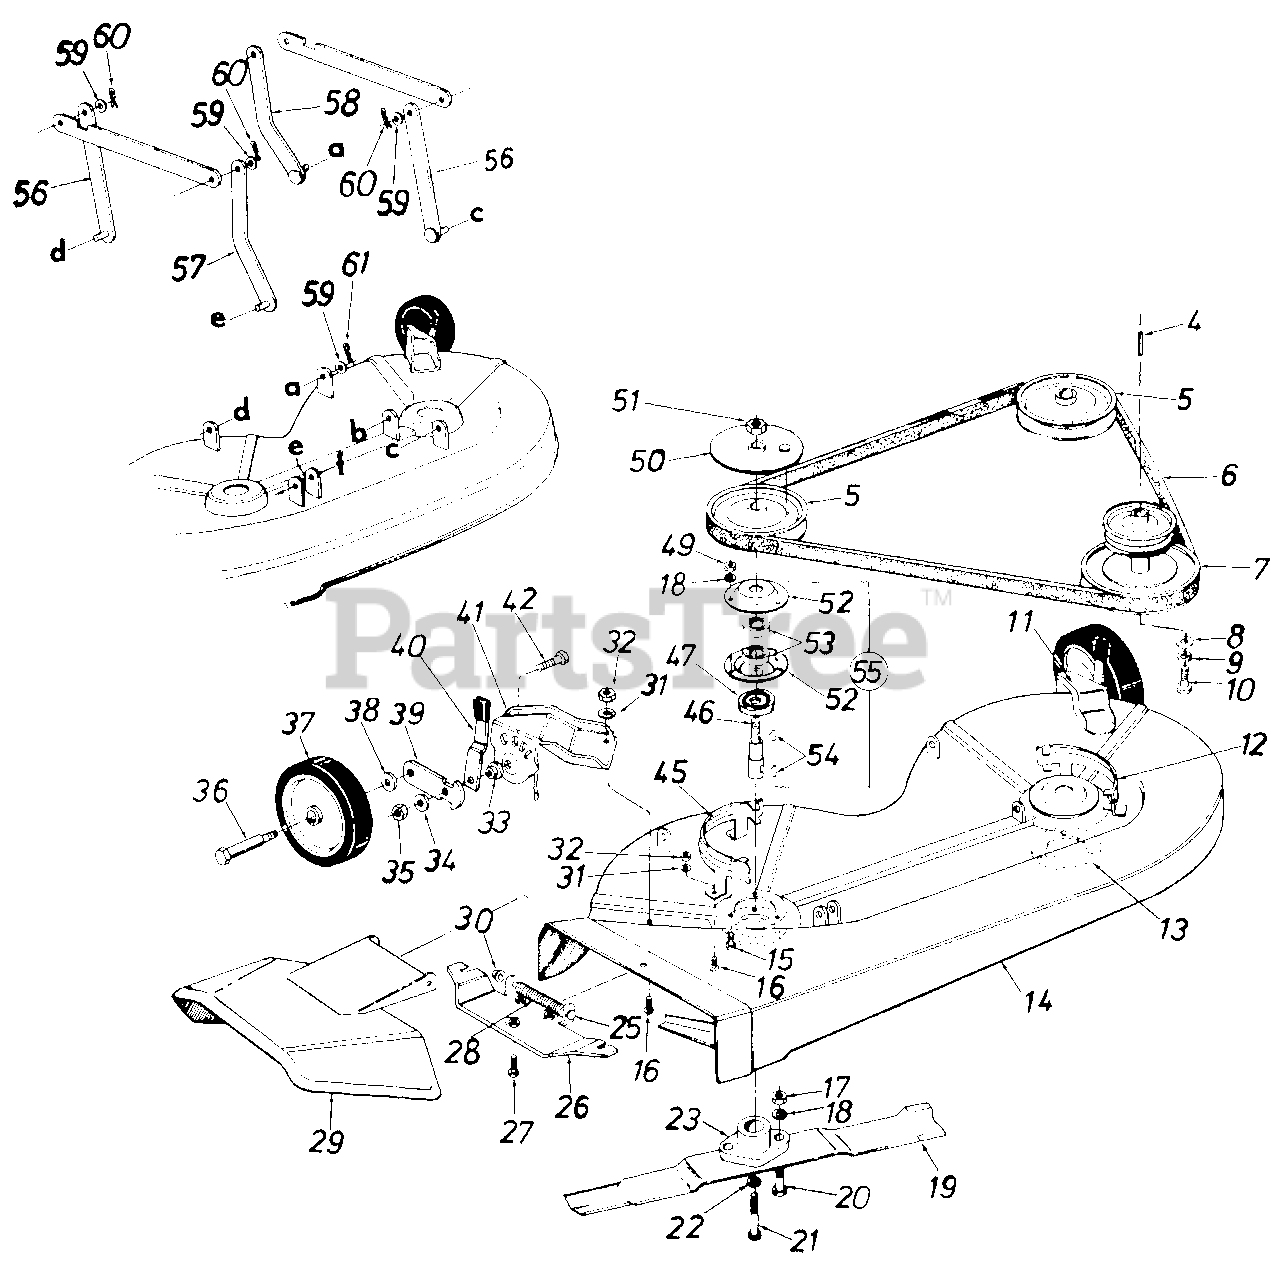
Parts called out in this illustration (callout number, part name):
4	Sq. Key 1/4" x 1/4" x 2.0"
5	Pulley 4.75" O.D.
6	"V"-Belt 21/32 x 67" Lg.
7	See Lawn Tractor Manual
8	Fl-Wash. 7/16" I.D. x 1.25 O.D. x .180
9	L-Wash. 7/16" I.D.
10	Hex Bolt 7/16-20 x 1.50" Lg.
11	Wheel Brk't. L.H.
12	Belt Guard L.H.
13	Plate Deck Reinforcement
14	34" Deck Ass'y.
15	Hex Sems Bolt 5/16-18 x 1.00" Lg.
16	Hex Bolt 1/4-20 x .50" Lg.
17	Hex Nut 5/16 24 Thd.
18	L-Wash. 5/16" I.D.
19	17" Blade
20	Hex Bolt 5/16-24 x 1.00n Lg. Grade 5
21	Hex Bolt 3/8-24 x 1.50n Lg. Grade 5
22	L-Wash. 3/8 I.D.
23	Blade Adapter Kit
25	Hinge Pin
26	Adapter Plate
27	Hex Wash. Self-Tap Scr. 1/4-20 x .50" Lg.
28	Torsion Spring
29	Chute Cover Ass'y. Comp.
30	Push Nut 1/4" Rod
31	L-Wash. 1/4" l.D.
32	Hex Nut 1/4-20 Thd.
33	Shld. Spacer
34	Bell-Wash. .400" I.D. x 1.13"
35	Hex Top L-Nut 3/8-16 Thd.
36	Shld. Bolt .498" Dia. x 1.53"
37	Plastic Wheel 5.0" x 1.38"
38	Bell-Wash. .400" I.D. x .88n
39	Pivot Bar
40	Spring Lever Ass'y. w/Knob
41	Wheel Brk't. R.H.
42	Hex Bolt 3/8-16 x 1.00n Lg.
45	Belt Guard R.H.
46	Blade Spindle
47	Bearing Shield
49	Hex Nut 5/16-18 Thd.
50	Brake Disc
51	Hex Jam L-Nut 5/8-11 Thd.
52	Bearing Housing
53	Ball Bearing .787" l.D. x 1.85" O.D.
54	#6 Hi-Pro Key 5/32" x 5/8" Dia.
55	Blade Spindle Ass'y.
56	Link Deck Hanger Assy.
57	Link Deck Hanger Ass'y.
60	Inter. Cotter Pin 3/8" Dia.
61	Inter. Cotter Pin .50" Dia.
